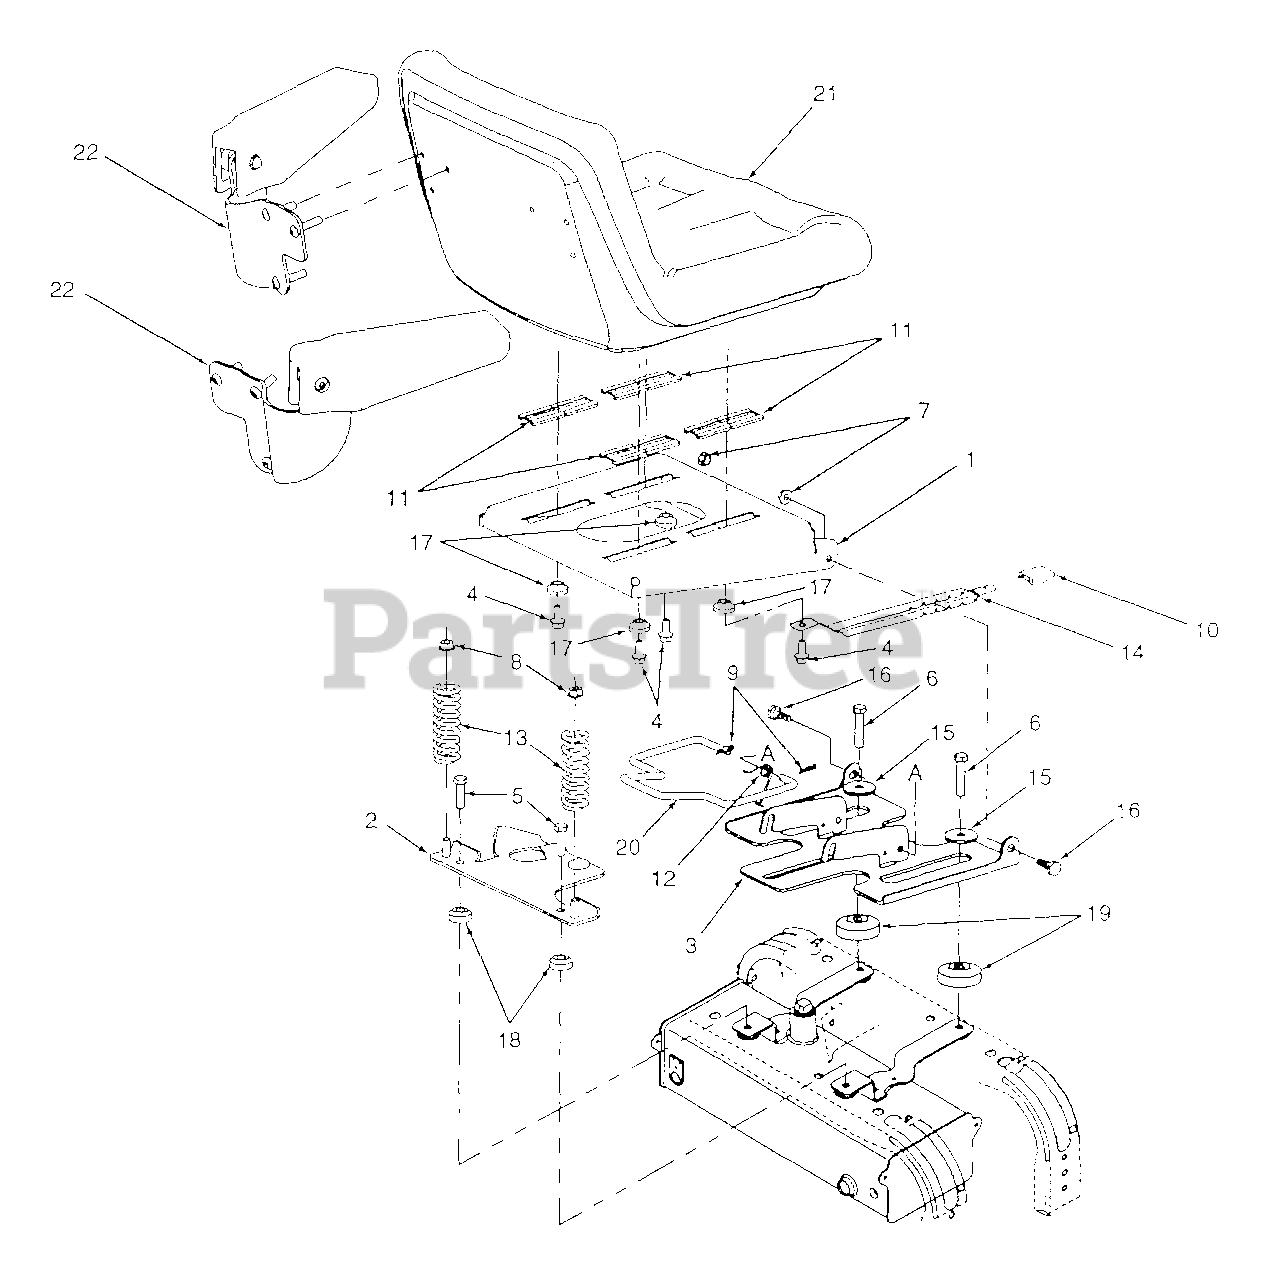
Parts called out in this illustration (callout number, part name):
1	Seat Base
4	Screw, Hex Wash Hd Tapp 5/16-18 x .75
5	Screw, Hex Cap 3/8-16 x 1.5 GR5
6	Screw, Hex Cap 3/8-16 x 1-3/4 GR5
7	Nut, Hex Flange Lock 5/16-18 GR5
8	Nut, Hex Flange Lock 3/8-16 GR5
9	Pin, Internal Cotter
10	Knob, Seat Adjustment
11	Seat Slide
12	Spring, Torsion
13	Spring, Compression
14	Spring, Index
15	Washer, Flat, .390 x 1.5 x .134
16	Bolt, Shoulder .437 x .268:5/16-18
17	Spacer, Shoulder, .38 I.D.
18	Spacer, Shoulder
19	Spacer, Seat Pan Shoulder
20	Rod, Seat Pan Lock
21	Seat Assembly
22	Seat Arm
